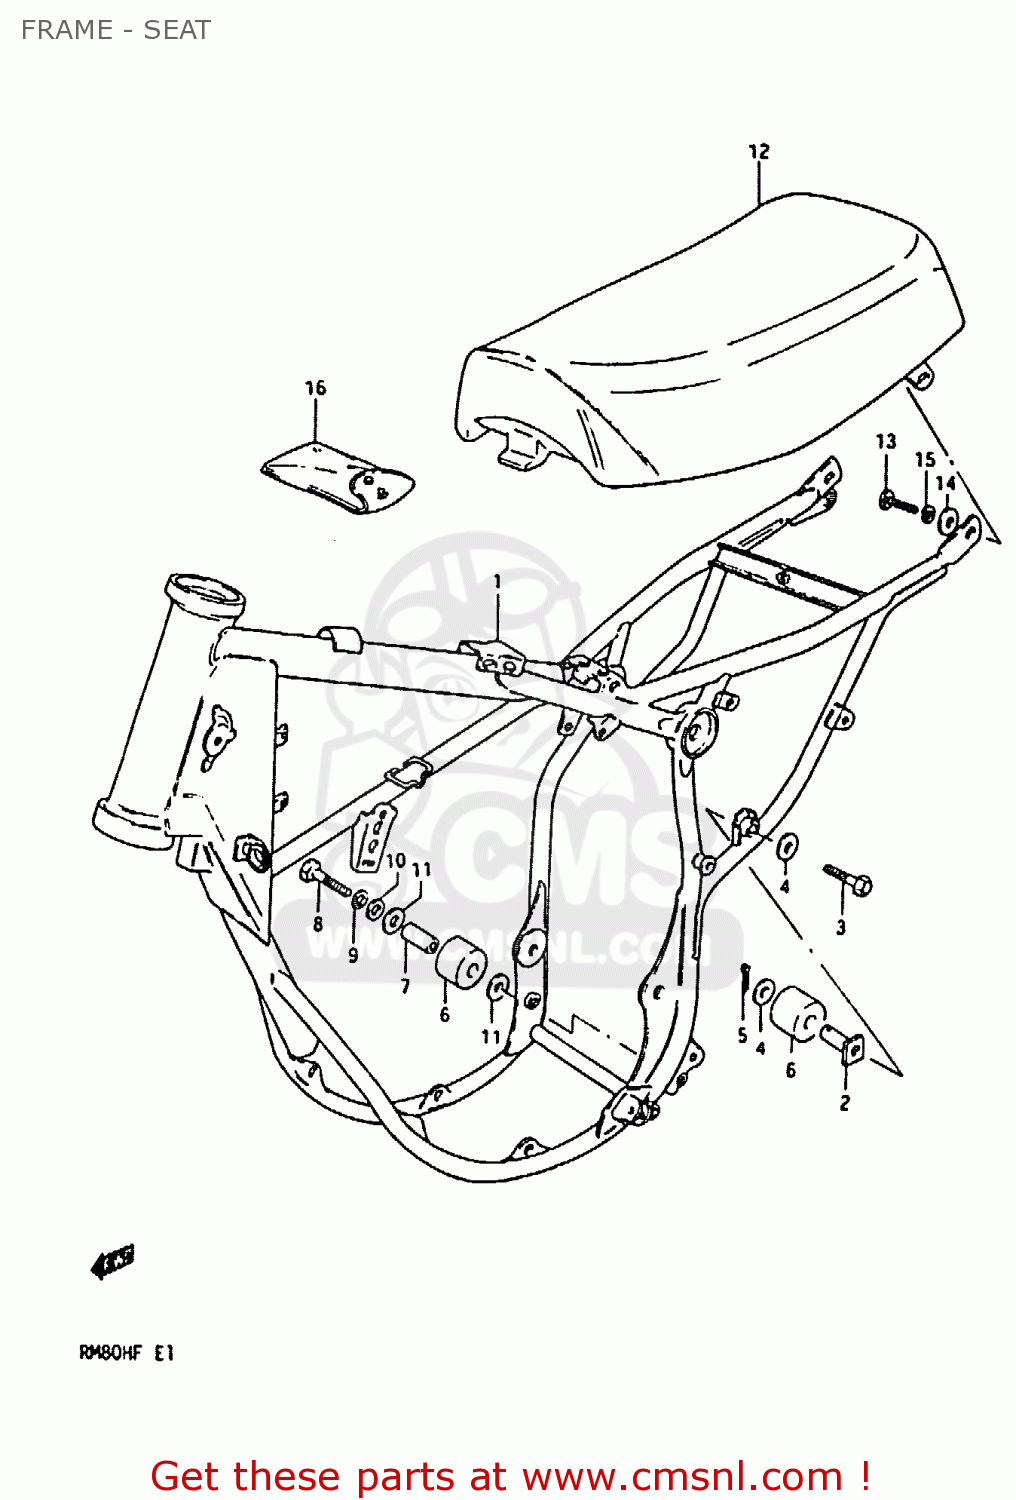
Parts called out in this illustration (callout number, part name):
1	FRAME (BLUE)
2	BOSS,CHAIN CONTROL
3	BOLT
4	WASHER
5	PIN 25X20
6	ROLLER,CHAIN LENGTH CONTROLLER
7	SPACER (6.5X10.5X29)
8	BOLT
9	WASHER,LOCK
10	WASHER, LOWER
11	WASHER
12	SEAT ASSY (BLUE)
13	BOLT
14	WASHER
15	LOCK WASHER
16	TOOL SET
